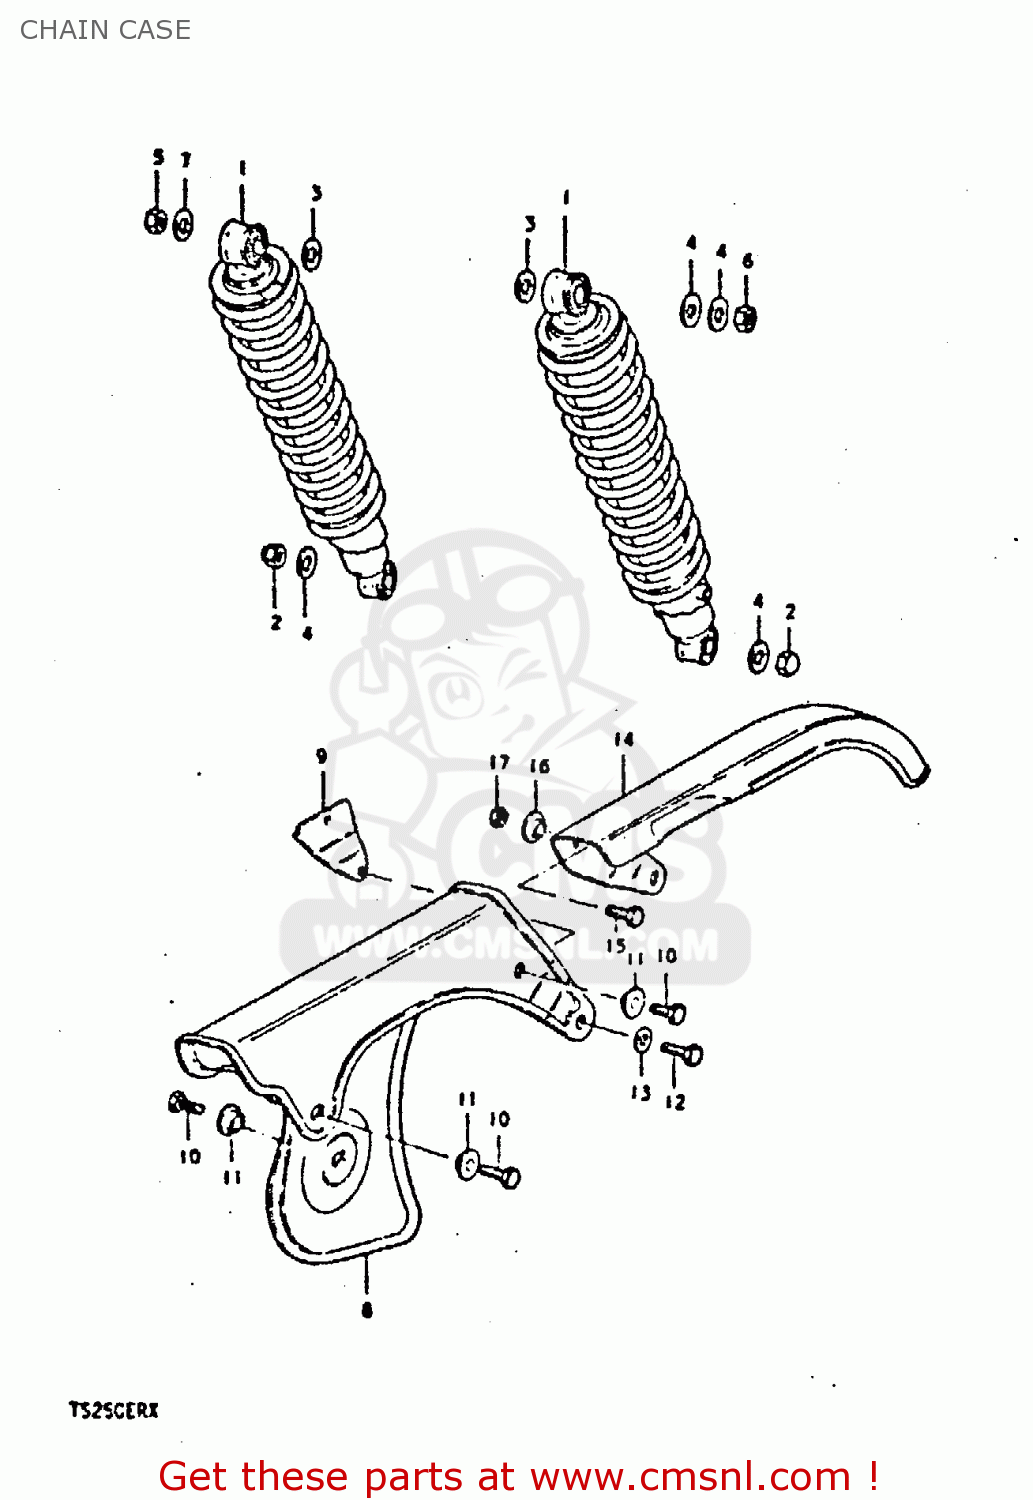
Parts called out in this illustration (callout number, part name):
1	ABSORBER ASSEMBLY,REAR SHOCK
2	NUT, LOWER LH
3	WASHER
4	WASHER
5	NUT
6	NUT
7	WASHER (12.5X24X3.2)
8	CASE,CHAIN
9	REINFORCEMENT,CHAIN CASE
10	BOLT(6X8)
11	WASHER
12	BOLT
13	WASHER
